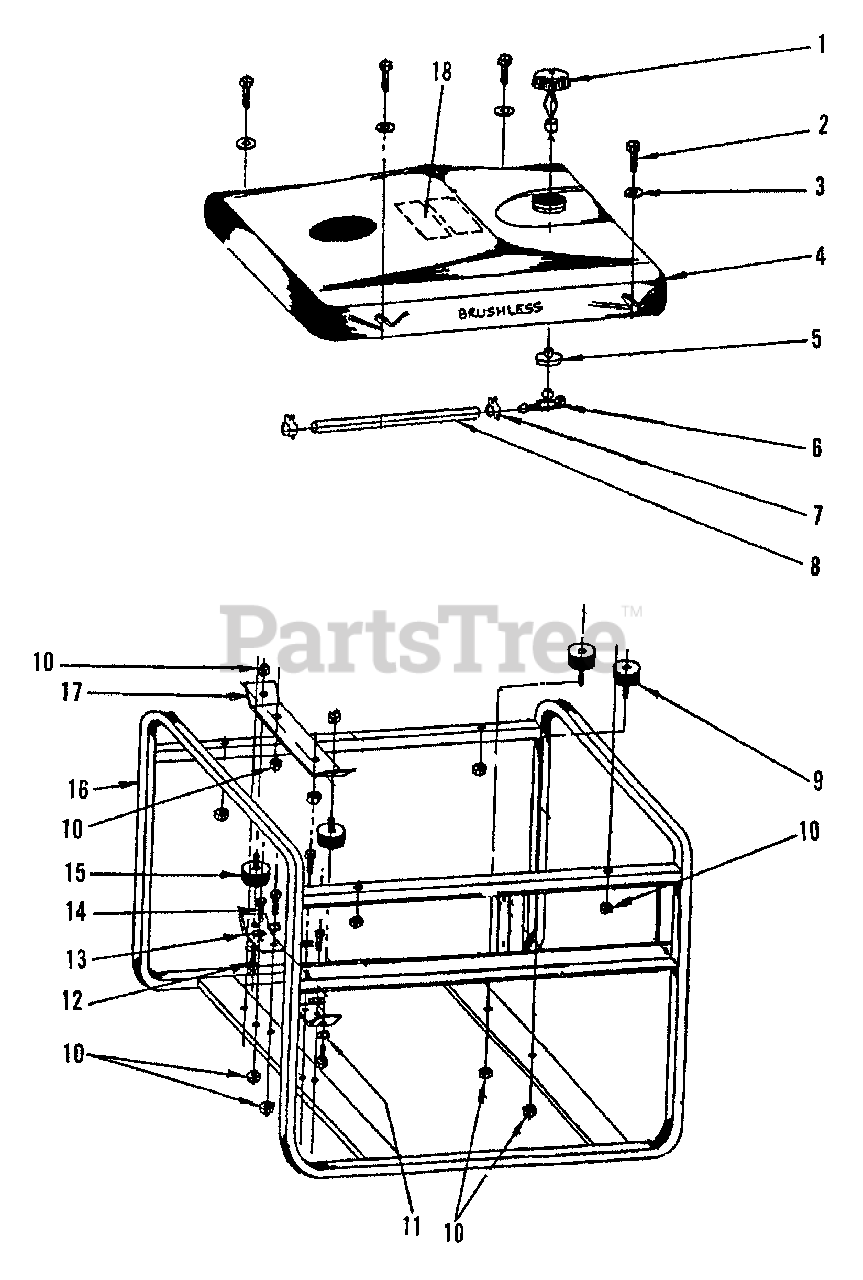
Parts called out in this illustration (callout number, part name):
1	CAP, FUEL
2	HHS 5/16-18X1.75
3	LOCKWASHER - 5/16"
4	TANK, FUEL - 6 GALLON
5	GROMMET
6	VALVE, FUEL TANK
7	CLAMP - 1/4"
8	LINE, FUEL - 24"
9	ISOLATOR, VIBRATION
10	LOCKNUT - 5/16-18
11	LOCKWASHER - 5/16"
12	5/16-18X5/8 HHS
13	BRACKET, FOCUS
14	5/16-18X7/8 HHS
15	ISOLATOR, VIBRATION
16	FRAME
17	RAIL, FOCUS
18	LABEL - SAFETY
